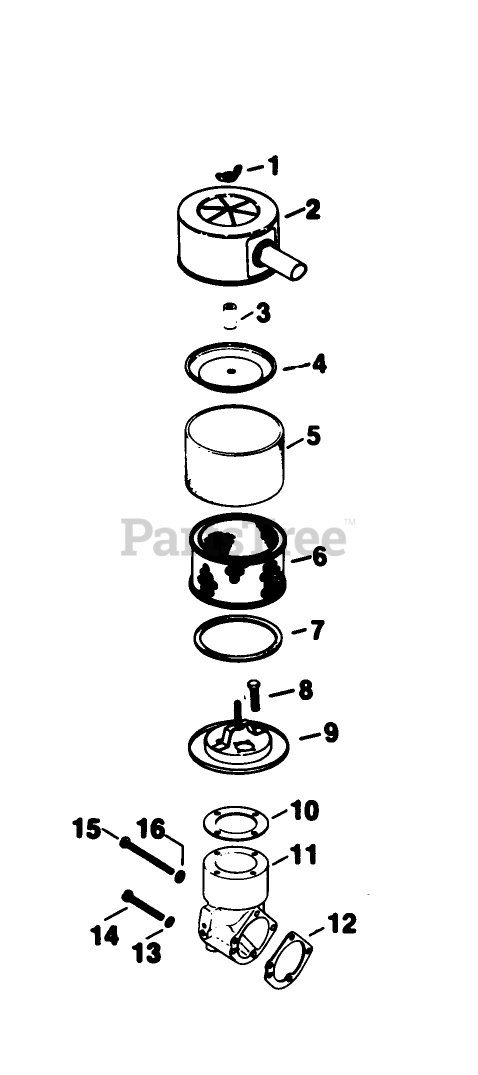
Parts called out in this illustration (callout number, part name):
1	Nut-Wing
2	26 Cover-Air Cleaner
4	Cover-Inner
5	Element
6	Element
7	Seal
8	Screw-H.C.
9	Base-Air Cleaner
10	Gasket-Air Cleaner
11	Elbow-Air Intake
12	Gasket
13	Washer
14	Screw-R.H.M.
15	Screw-R.H.M.
16	Washer
